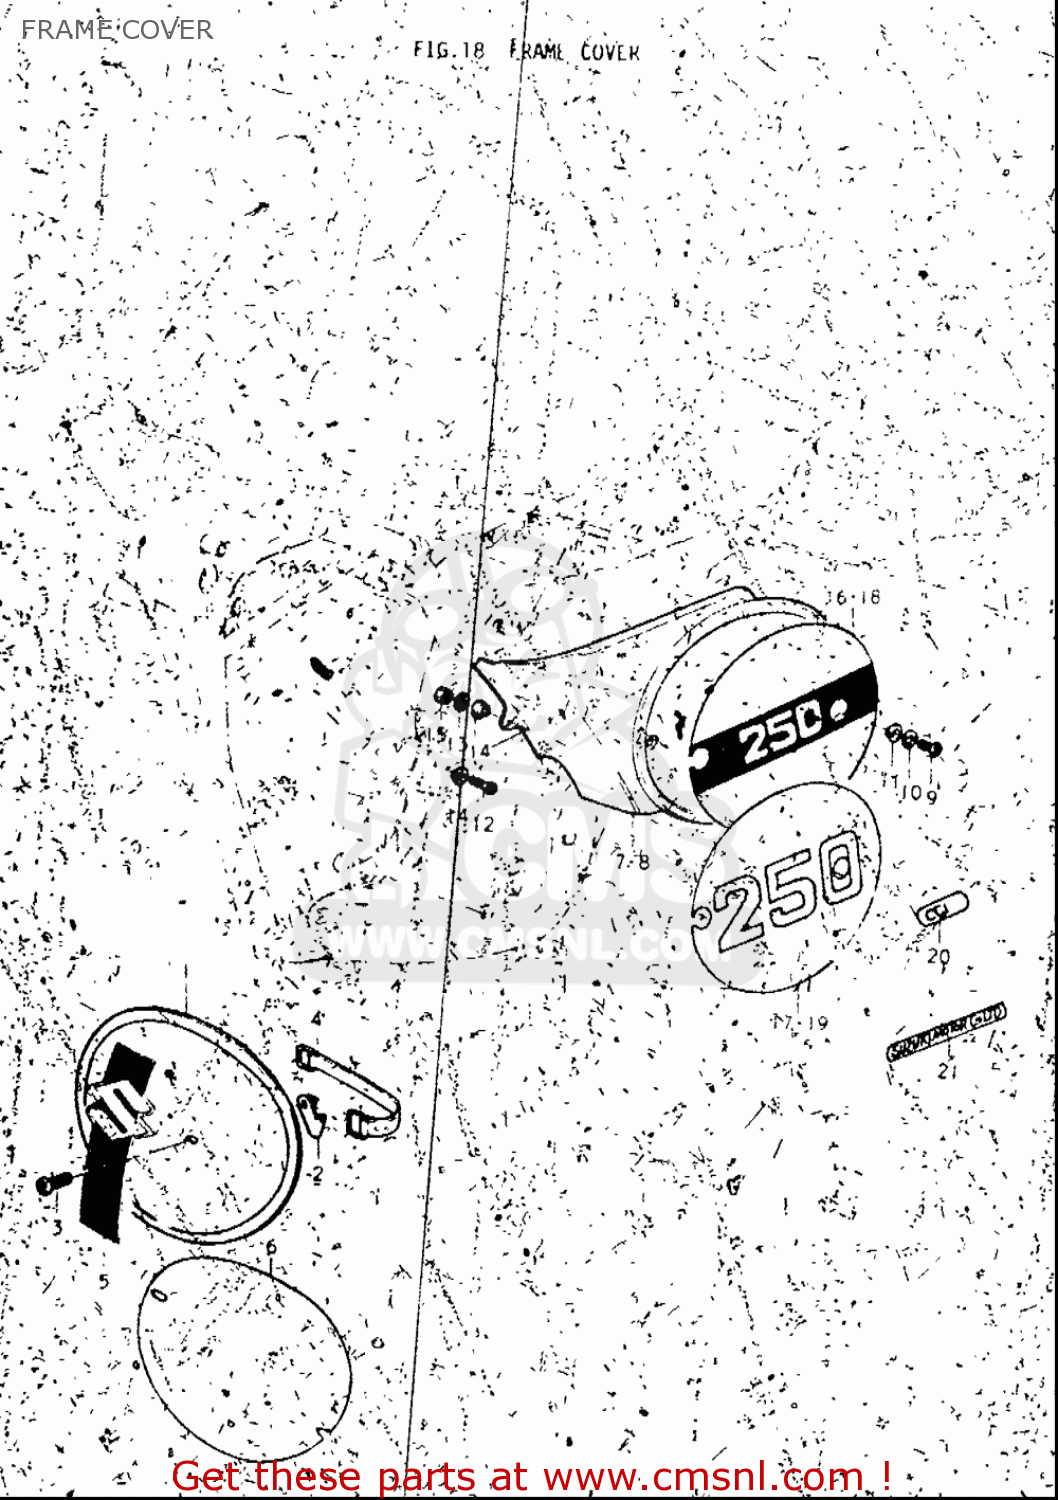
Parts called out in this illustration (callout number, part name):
3	SCREW 6X12
4	BAND
9	SCREW 6X12
10	WASHER,LOCK
11	WASHER
13	WASHER,LOCK
14	WASHER
20	EMBLEM,CCIS
